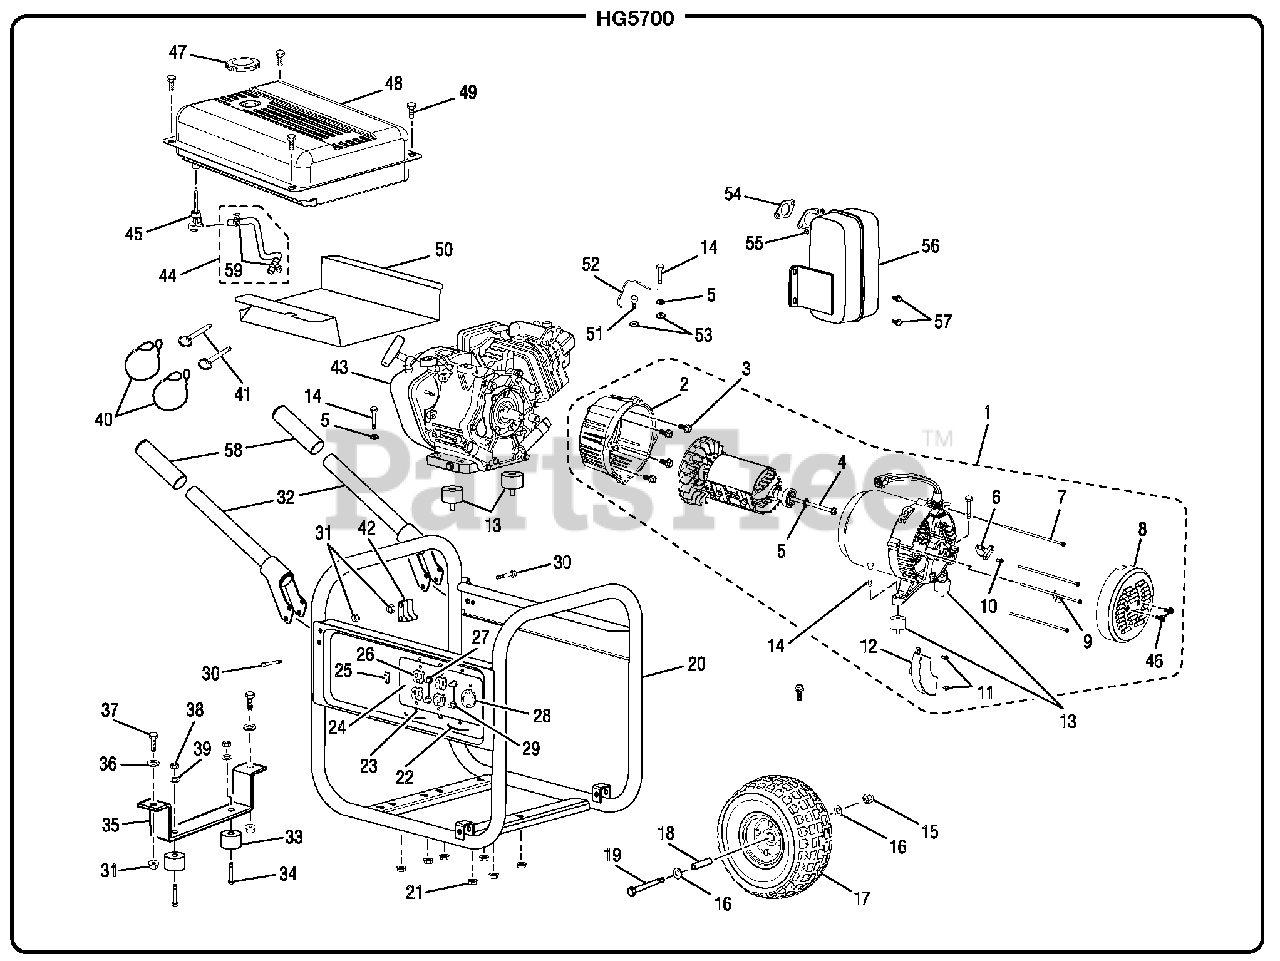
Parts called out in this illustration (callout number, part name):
1	Generator Head Assembly (Inc. Key Nos. 2 & 4-12)
2	Adapter Housing
3	Bolt, Wiz (3/8-18 x 1-1/4 in.)
4	Bolt (5/16-24 x 6-5/8 in., Hex Hd.)
5	Lock Washer (5/16 in.)
6	Brush Assembly
7	Bolt, Stator 5.7kW
8	Brush Cover
9	Ground Lug
10	Bolt, Mounting Brush Assembly
11	Bolt, Mounting AVR
12	Automatic Voltage Regulator
14	Bolt (5/16-18 x 1 1/2 in., Hex Hd.)
15	Lock Nut (3/8-16)
16	Washer, Flat (3/8 in.)
17	Wheel (10 in.)
18	Wheel Spacer
19	Bolt (3/8-16 x 4-1/4 in.)
20	Frame Assembly
21	Flange Nut (5/16-18)
22	Cord Retainer
23	Screw (6-20 x .38 in.)
24	Wire Panel
25	Switch, Engine Stop
26	Recepticle (120 V, 20 Amp)
27	Circuit Breaker 20 Amp Single Pole
28	Recepticle (240 V, 30 Amp)
29	Circuit Breaker 25 Amp Single Pole
30	Bolt (1/4-20 x 1 in)
31	Lock Nut (5/16-18)
32	Handle Assembly (Inc. Key No. 58)
33	Rubber Foot
34	Bolt (1/4-20 x 1/2 in.)
35	Front Foot Bracket
36	Washer (5/16 in.)
37	Bolt (5/16-18 x 1 in. Hex Hd.)
38	Nut, Nyloc (1/4-20)
39	Washer (1/4 in.)
41	Handle Lock Pin
42	Handle Bracket Spacer
43	Engine (Yamaha OHV)
44	Fuel Line Assembly (Incl. Key No. 59)
45	Fuel Shut Off with Filter
48	Fuel Tank Assembly
49	Screw (1/4-20 x 1 in.)
50	Heat Shield
51	Bolt (5/16-18 x 3/4 in., Hex. Hd.)
52	Ground Wire Assembly
53	Washer (5/16 in.) External Star
55	Nut (8 mm)
57	Bolt (5/16-24 x 5/8 in.)
58	Handle Grip
59	Fuel Line Clamp
